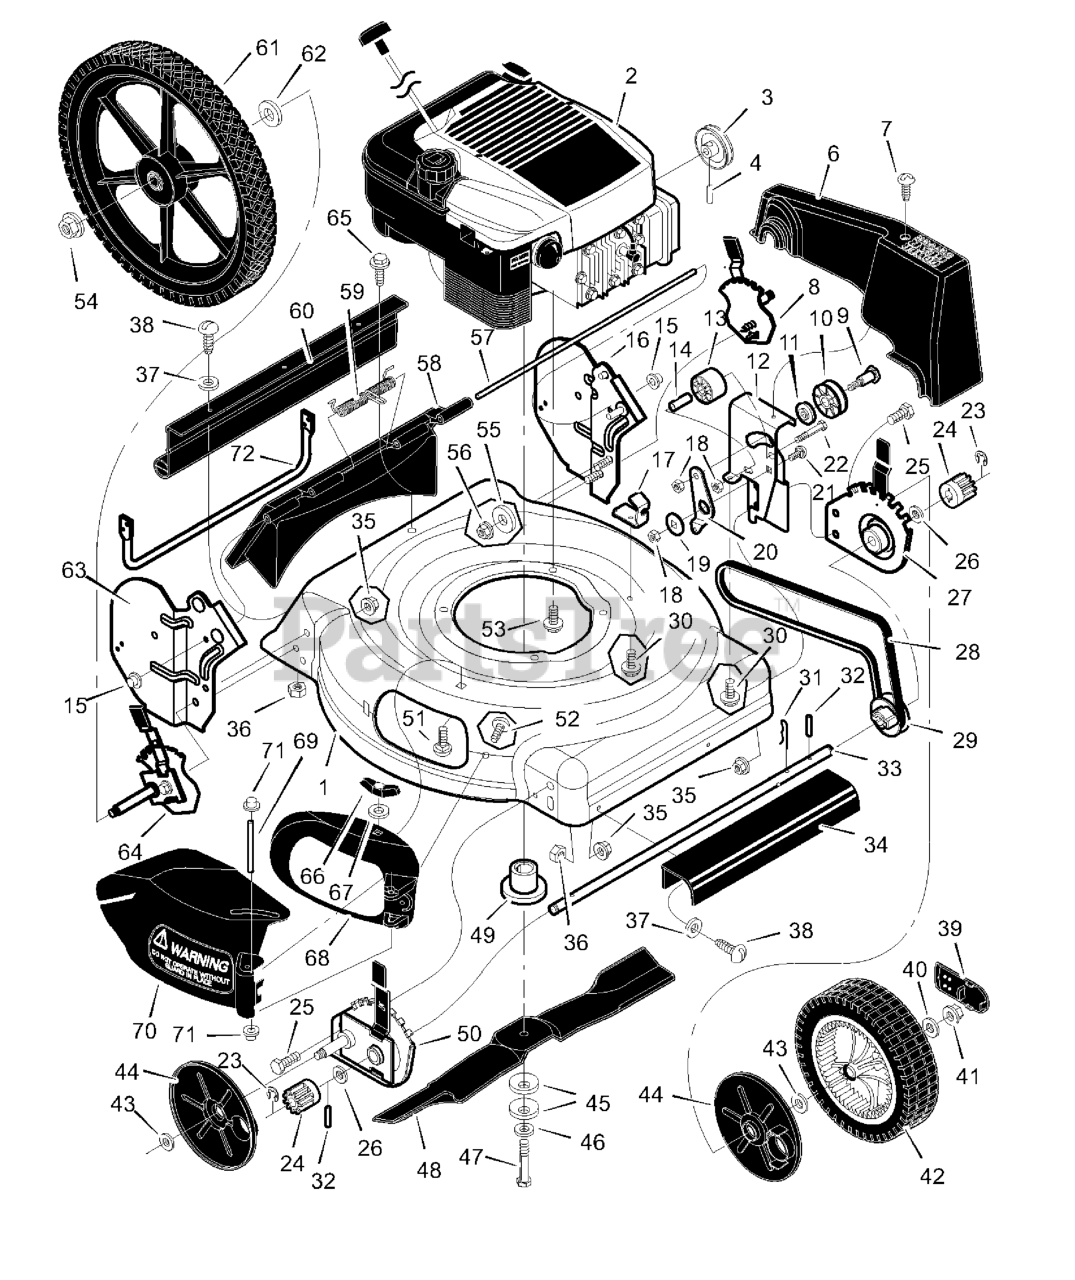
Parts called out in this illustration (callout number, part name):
1	Housing
2	Engine *
3	Pulley, Engine
4	Pin, Spring
6	Cover, Belt
8	Adjuster, Left Rear Height
9	Bolt, Shoulder
12	Bracket, Idler Support
13	Pulley, Idler
14	Bearing
15	Nut, Push
16	Bracket, Left Handle
17	Bracket, Cable
18	Nut, Hex
20	Arm, Idler
21	Bolt, Carriage
22	Bolt, Shoulder
24	Gear, Pinion
25	Bolt
27	Adjuster, Left Front Height
29	Pulley, Axle
31	Pin, Hair
32	Pin, Spring
34	Cover, Axle
35	Nut, Flange
36	Nut, Hex
39	Hub Cap
40	Washer
41	Nut, Flange
42	Wheel, Drive
44	Cover, Dust
45	Washer, Belleville
49	Adapter, Blade
50	Adjuster, Right Front Height
51	Bolt, Carriage
53	Bolt, Engine
54	Nut
55	Washer
56	Nut, Flange
57	Rod, Pivot
58	Door, Rear
60	Guard, Rear
61	Wheel, Rear
63	Bracket, Right Handle
64	Adjuster, Right Rear Height
66	Wingnut
67	Retainer, Push
69	Pin, Pivot
70	Deflector, Chute
71	Push On Cap
